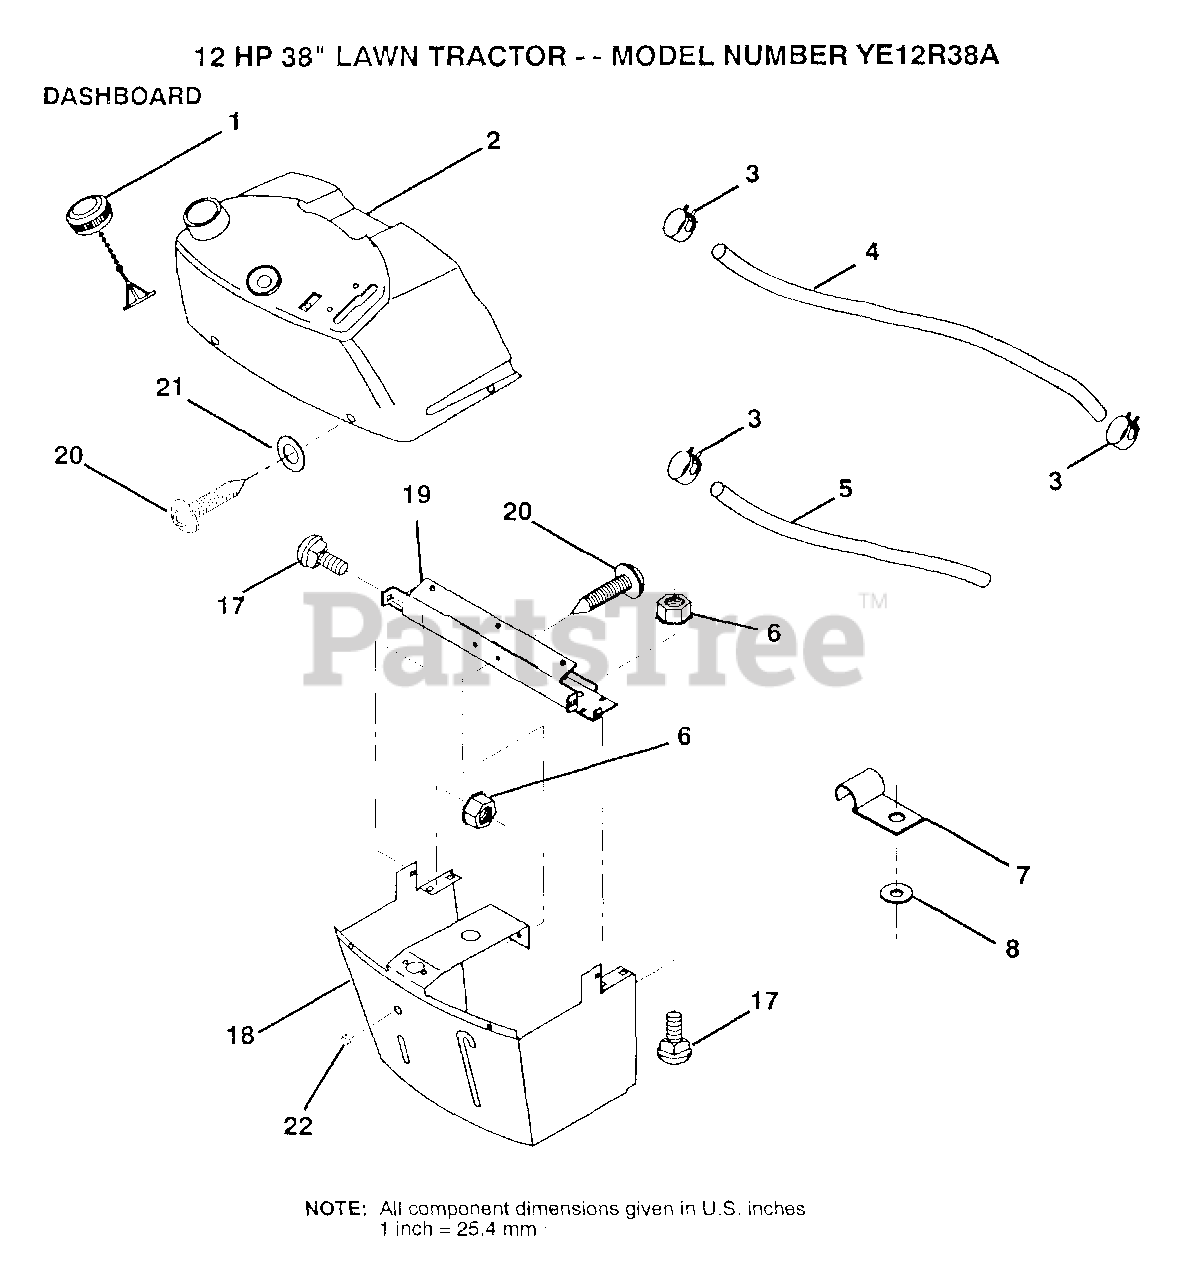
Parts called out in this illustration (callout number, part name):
3	HOSE CLAMP
5	FUEL LINE T
6	NUT
7	CLIP T
8	WASHER PM
17	BOLT
18	SUPT ASM DASH
19	CROSS BRACE
22	PLUG DOME
